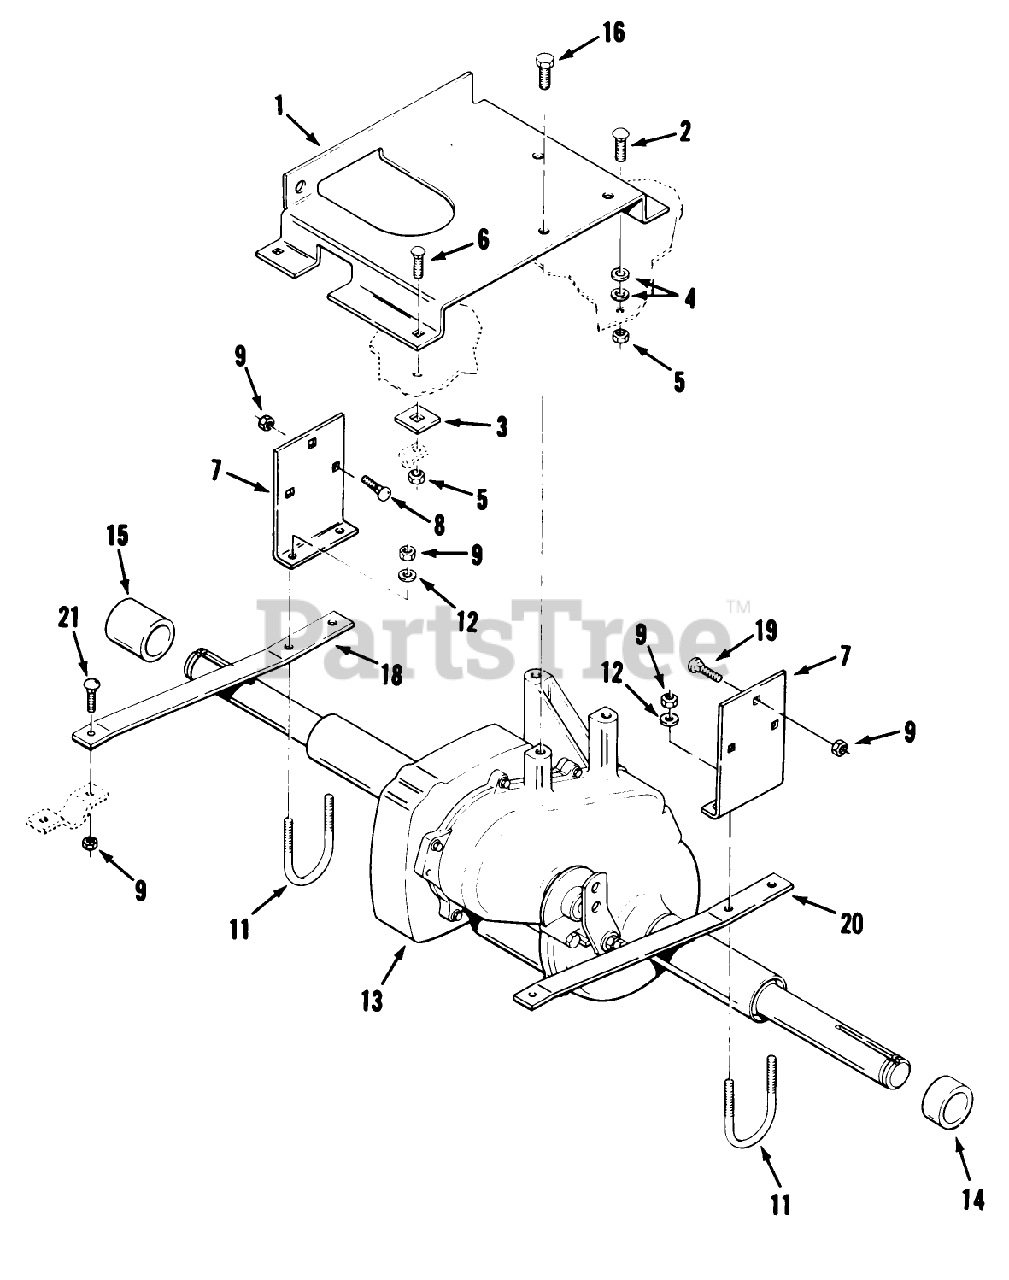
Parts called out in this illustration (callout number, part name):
4	WASHER 5/16 SAE
11	U-BOLT AXLE MTG
12	WASHER 5/16 SAE
